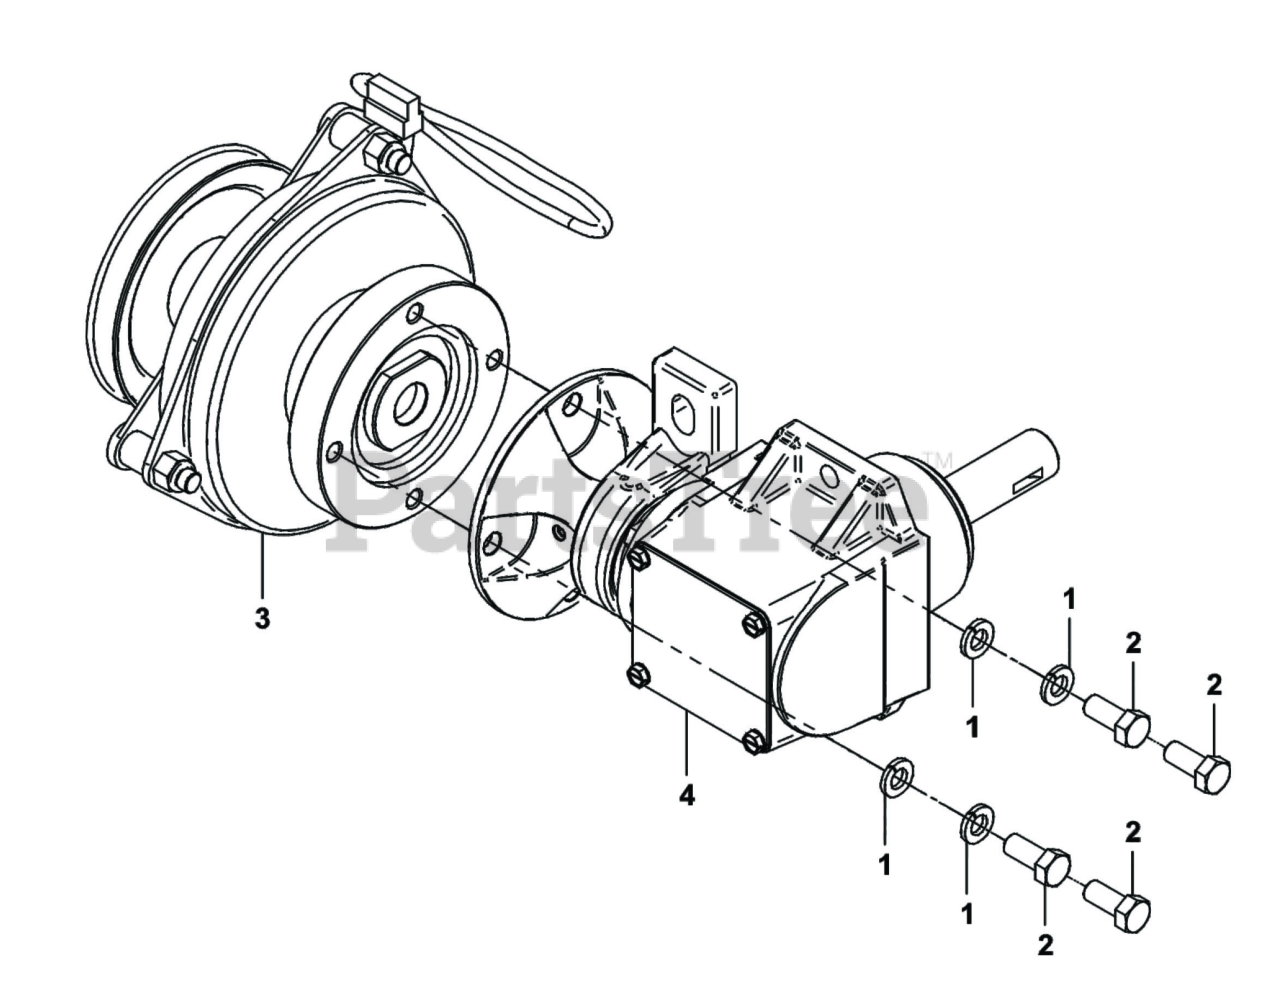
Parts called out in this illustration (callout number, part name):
1	LOCK WASHER 3/8
2	SCREW 3/8"-16 x .875" (GR8)
3	CLUTCH SUB ASSY
4	GEARBOX SUB ASSEMBLY
